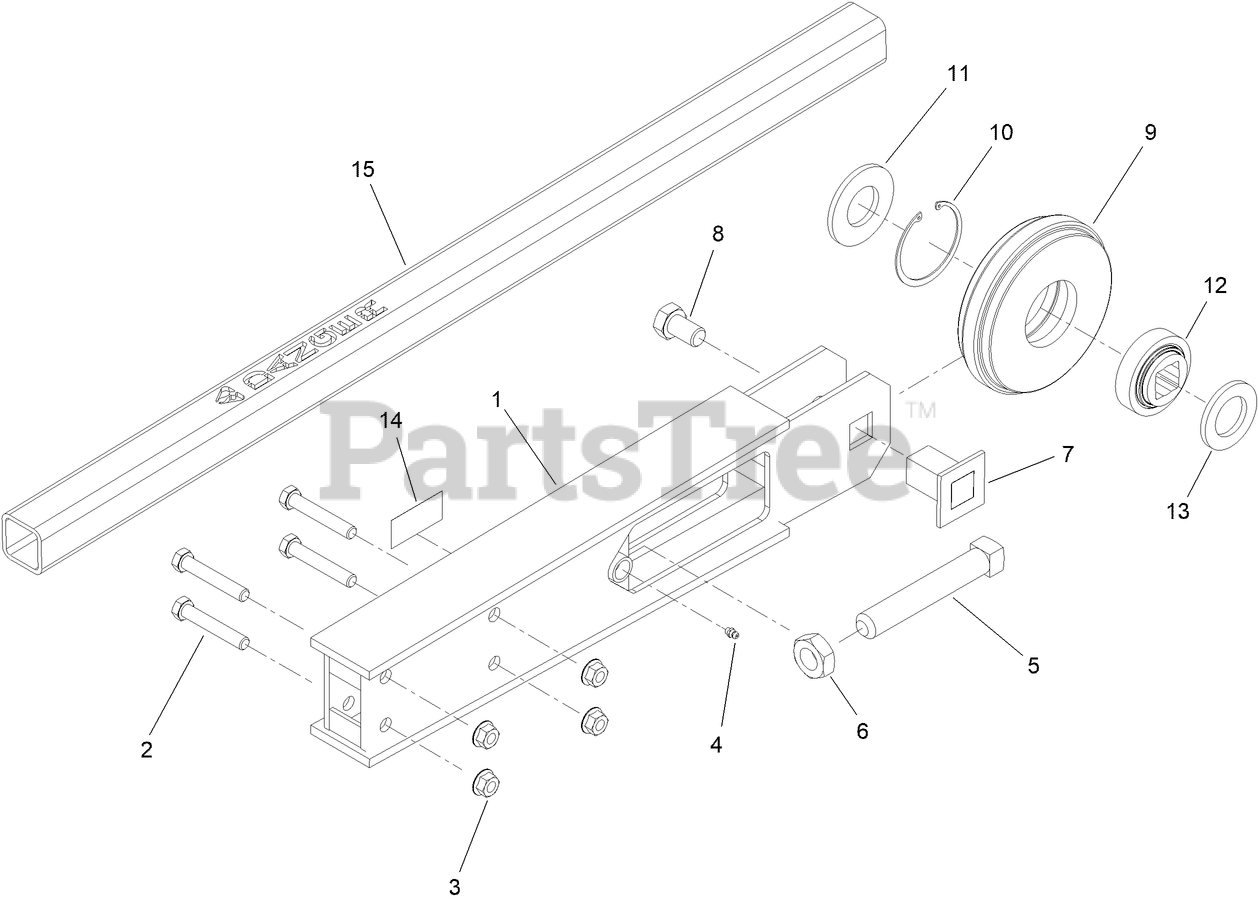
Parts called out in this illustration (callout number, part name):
1	ROLLER BOOM 24.0
2	SCREW-HF
3	NUT-HHF, WHIZ
4	FITTING-GREASE
5	SCREW-SET
6	NUT-HEX
7	IDLER SHAFT
8	LK BOLT
9	TAIL ROLLER
10	INTERNAL SNAP RING 3.149
11	DIRT SHIELD
12	BEARING
13	DIRT SHIELD
14	CHAIN TENSION ISO
15	DANGER RESTRAINT BAR SK 24.0
